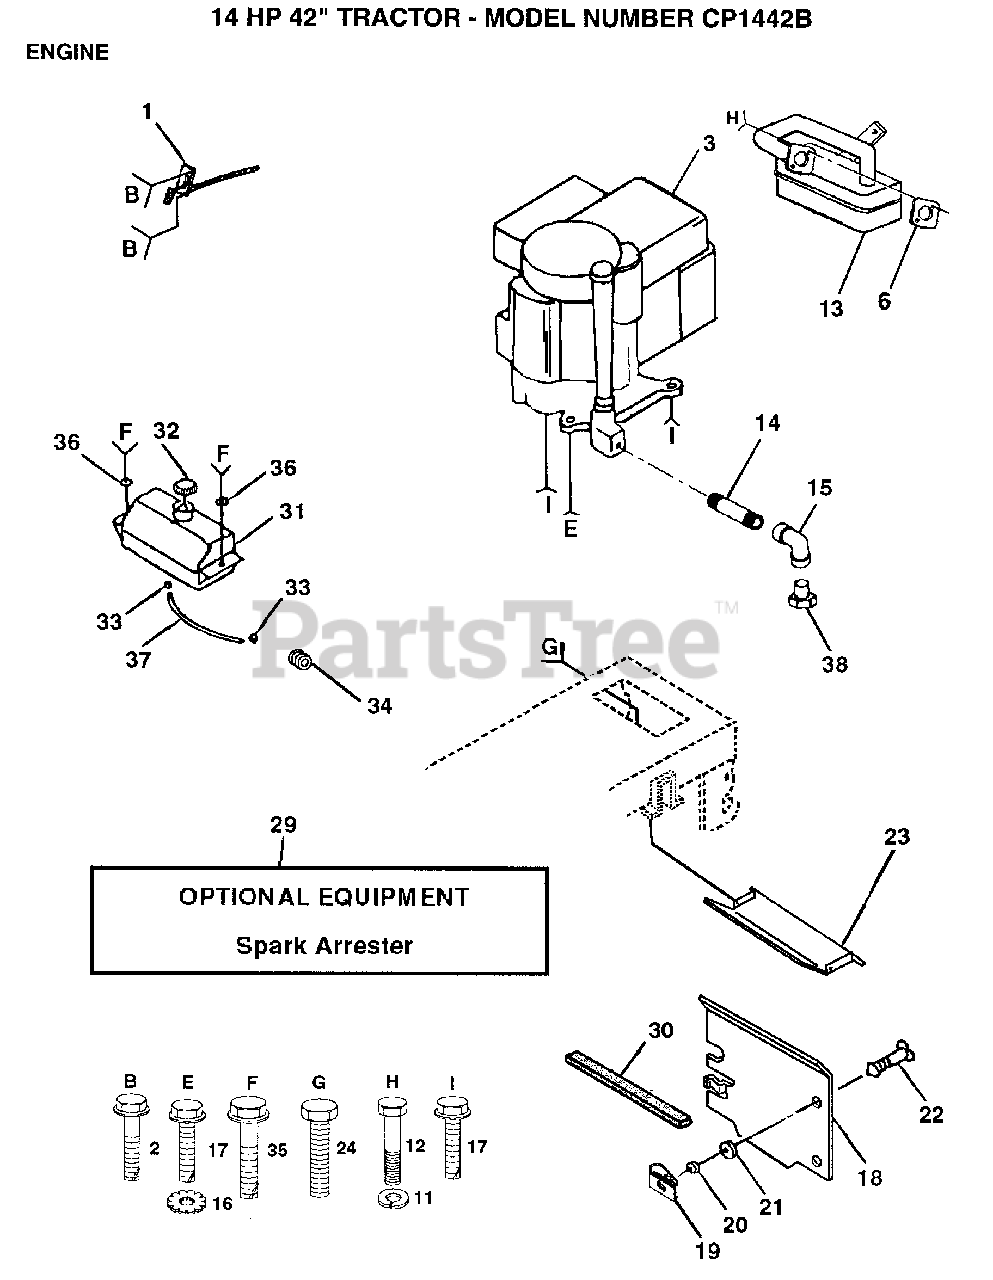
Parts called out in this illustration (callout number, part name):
1	CONTROL THROTTLE
2	SCREW LT
11	LOCKWASHER
12	SCREW
13	MUFFLER
14	PIPE NIPPLE
15	ELBOW
16	LOCKWASHER
17	SCREW
18	SHIELD HEAT
19	RECEPTACLE LT
20	RETAINER LT
21	WASHER
22	STUD.1/4.TURN
23	HEAT SHIELD
24	SCREW
31	TANK.FUEL.LT.
32	CAP ASM FUEL
33	HOSE CLAMP
35	SCREW HEX CRT
36	WASHER
37	LINE FUEL
